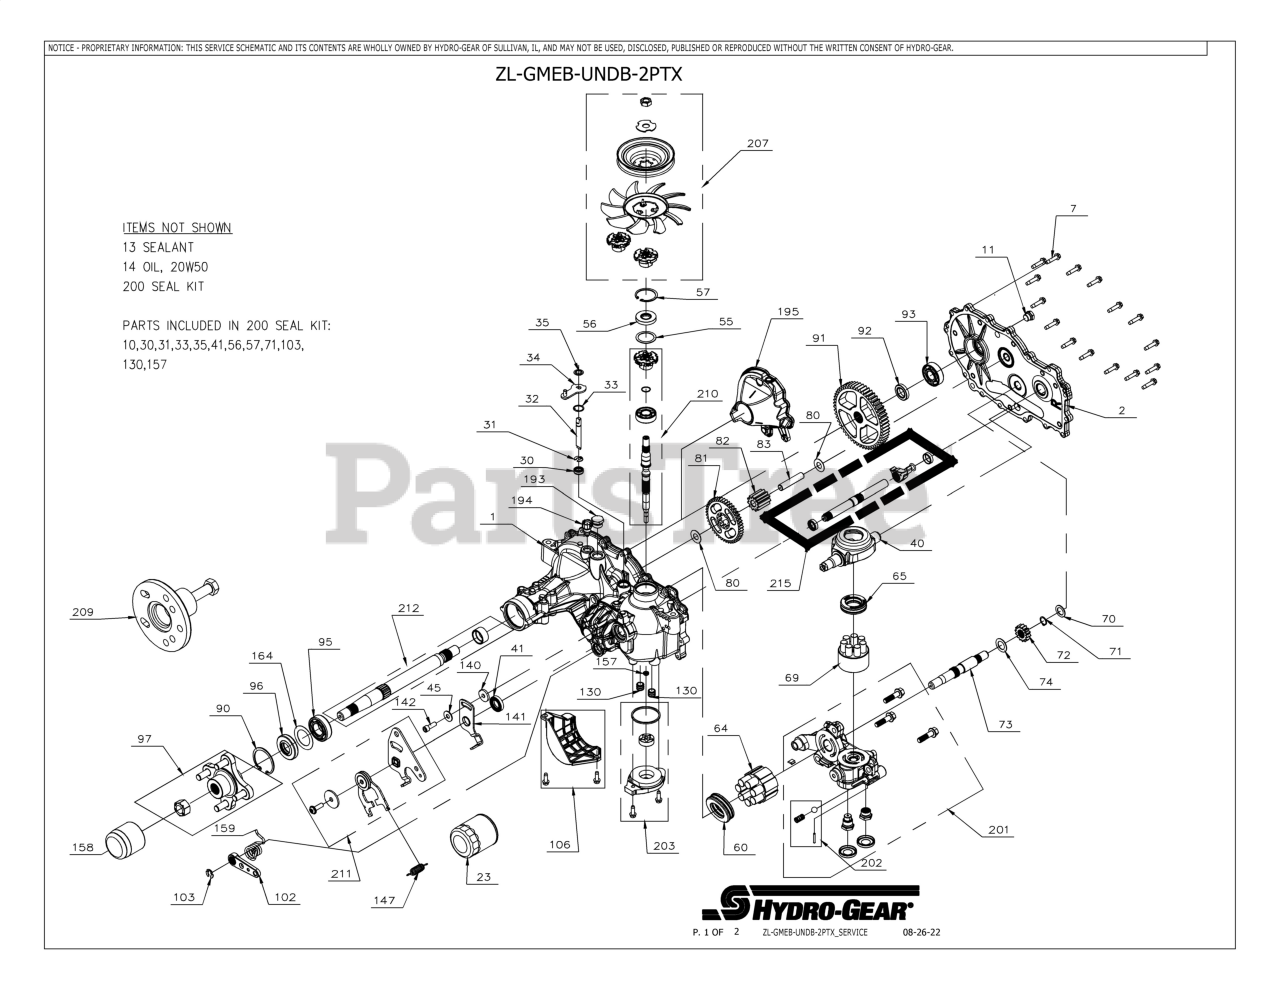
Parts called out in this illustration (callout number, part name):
1	KIT, HOUSING, MAIN, RH, CHRG, CNTL
2	KIT, SIDE COVER, RH
7	SCREW,HEX WASHER 1/4-20X1.125
11	PLUG EXT HEX VENT 9/16 18
13	SEALANT TUBE 10.1OZ.
14	FLUID, HYDRO 15W50 QT
14	FLUID, HYDRO 20W50 QT
23	FILTER, HYDRO-GEAR 2800 TRANS
30	Seal, lip .375 x 375 x 325
31	RING. RETAINING
32	ROD, BYPASS
33	RING, RET .750
34	ARM, BYPASS
35	RING, RTNG .
40	TRUNNION, SWASHPLATE
41	SEAL, LIP 18X32X7
55	WASHER 1.23X1.56X.04
56	SEAL, LIP 17 X 40 X 7 HNBR
57	RING, RET 1.56 INT
60	HG THRUST BEARING (51462)
64	HG 16CC CYLINDER BLOCK (71579)
65	BEARING. THRUST 30 X 52 X 13
69	ASSY, BLOCK 7 PISTON
70	WASHER .63X1.0X.05
71	RING, RET 62 EXT
72	GEAR 14T STEEL
73	SHAFT, MOTOR
74	WASHER .71 X 1.16 X .04
80	WASHER .5X1.0X.032
81	GEAR 45 TOOTH
82	GEAR 11 TOOTH STEEL
83	PIN, JACKSHAFT
90	RING, RETAINING
91	GEAR 54 TOOTH
92	SPACER
93	KIT, BEARING
95	BEARING, BALL 25.4 X 52 X 15
96	SEAL, LIP
97	KIT, HUB 4 BOLT
102	HANDLE- ACTUATING
103	CLIP,BRAKE ARM HYDROGEAR 52027
106	KIT FILTER GUARD
130	TUBE CHARGE TRIPLE ORING
141	ARM, NEUTRAL RIGHT
142	SHCS 5/16-24X1 PATCH
147	SPRING, EXTENSION
157	KIT GEROTOR SEAL
158	CAP, AXLE
159	SPRING, TORSION, CW
164	WASHER, 1.355 x 2.035 x .021 FLAT
194	ASSEMBLY, FITTING 9/16-18 BREATHER
195	ASSEMBLY, TANK, EXPANSION, INTERNAL, RH
200	KIT, SEAL
202	KIT CHARGE RELIEF
203	KIT, CHARGE
207	KIT- FAN/PULLEY
209	HUB PULLER 5 BLT
210	KIT INPUT SHAFT
211	KIT RTN BIDIRECTIONAL
212	KIT SHAFT AXLE
215	KIT, OUTBOARD, RH ROT B / LH ROT A
